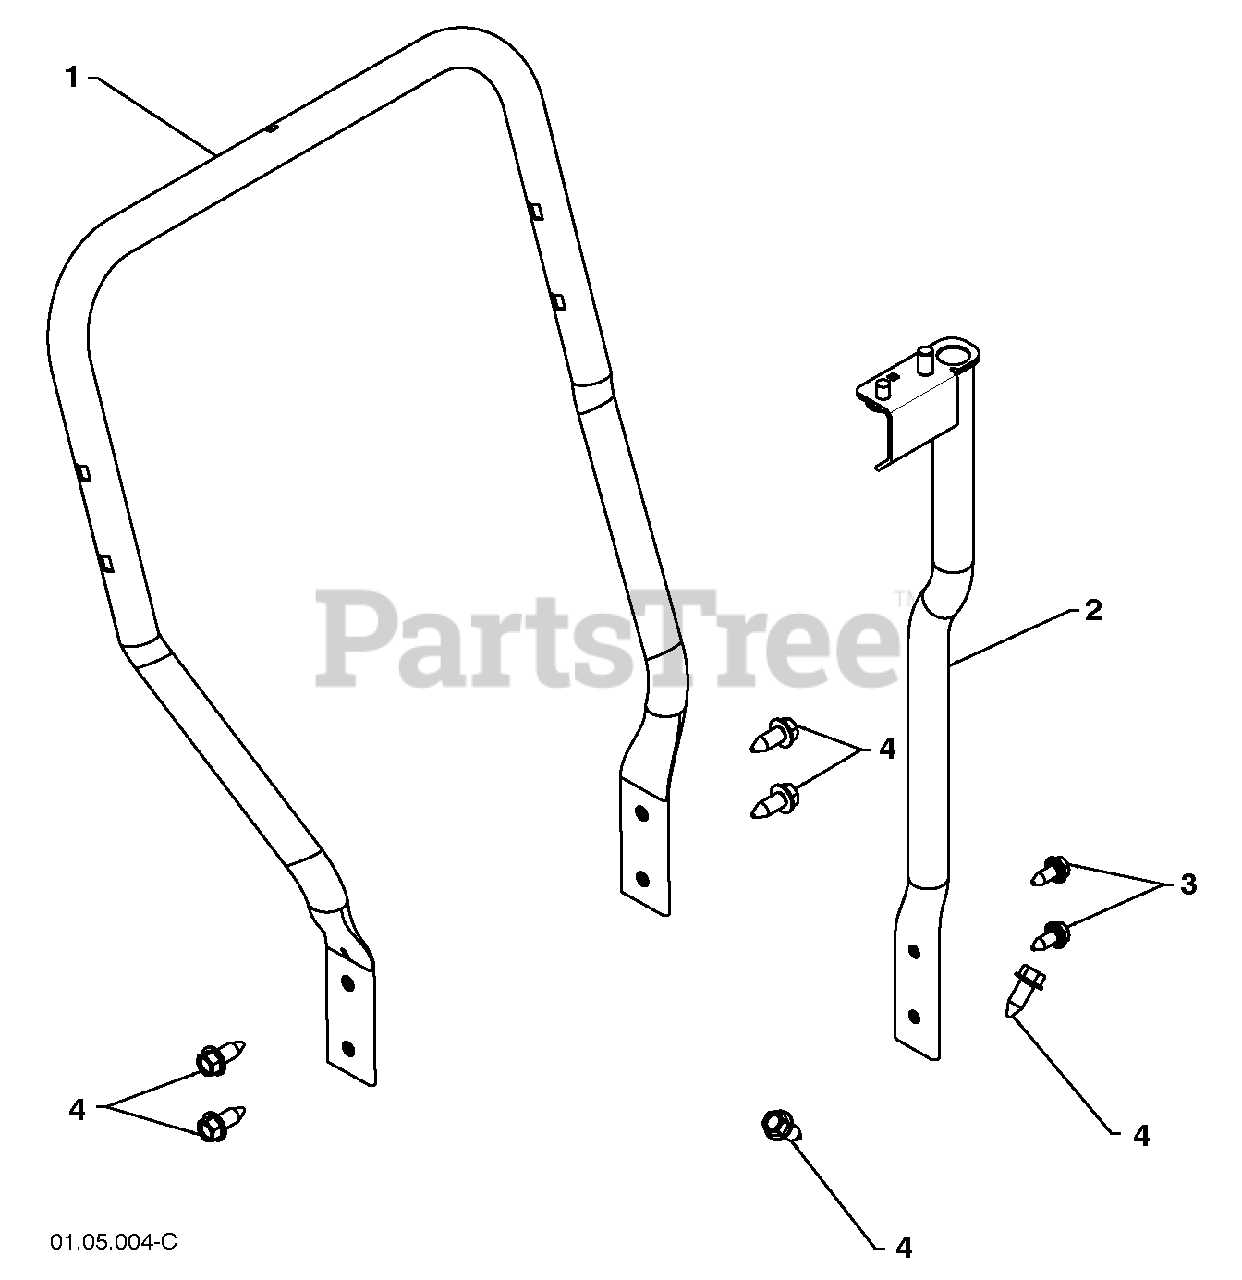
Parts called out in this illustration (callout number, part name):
1	LOWER TUBE
3	BOLT 5/16-18 X .750
4	SCREW 3/8-16 X 1.00
